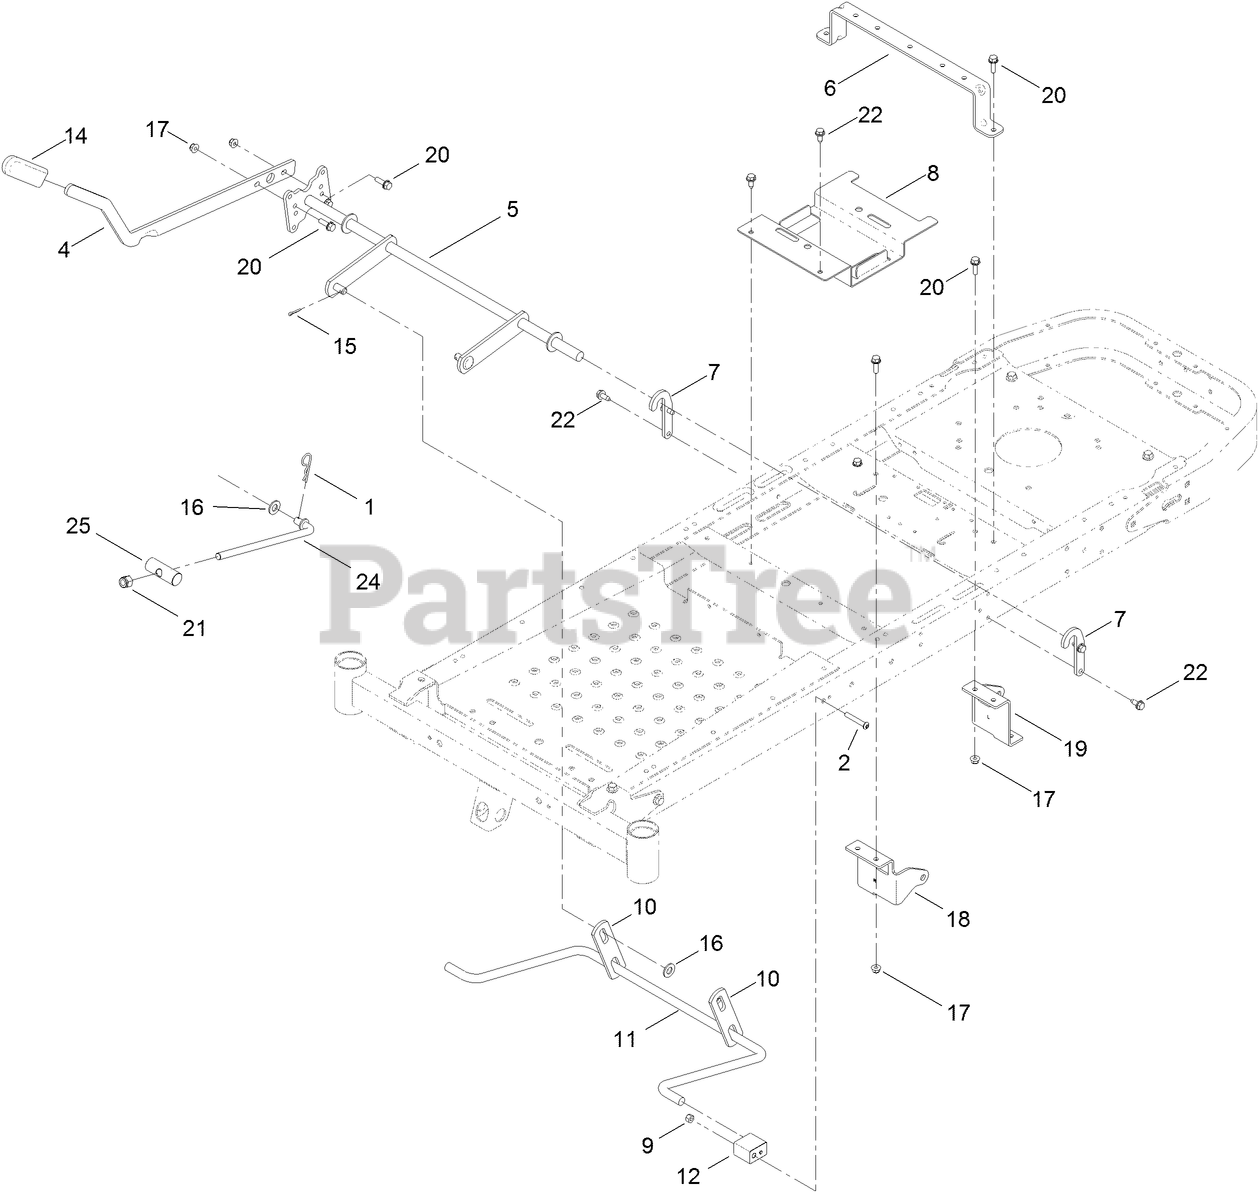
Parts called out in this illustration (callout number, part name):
1	PIN-COTTER
2	SCREW-HSBH
4	LEVER-LIFT
6	BRACE-SEAT, REAR (NARROW)
7	BRACKET-LIFT
8	BRACKET-BATTERY
9	NUT-LOCK, NI
10	LINK-LIFT
11	ARM-LIFT, REAR
12	BLOCK-PIVOT
14	GRIP-LEVER
15	PIN-COTTER
16	WASHER-FLAT
17	NUT-HF, NI
18	MOUNT-HYDRO, FRONT (RH)
20	SCREW-HHF
21	NUT-HEX
22	SCREW-HWHTF
25	PIN-PIVOT
